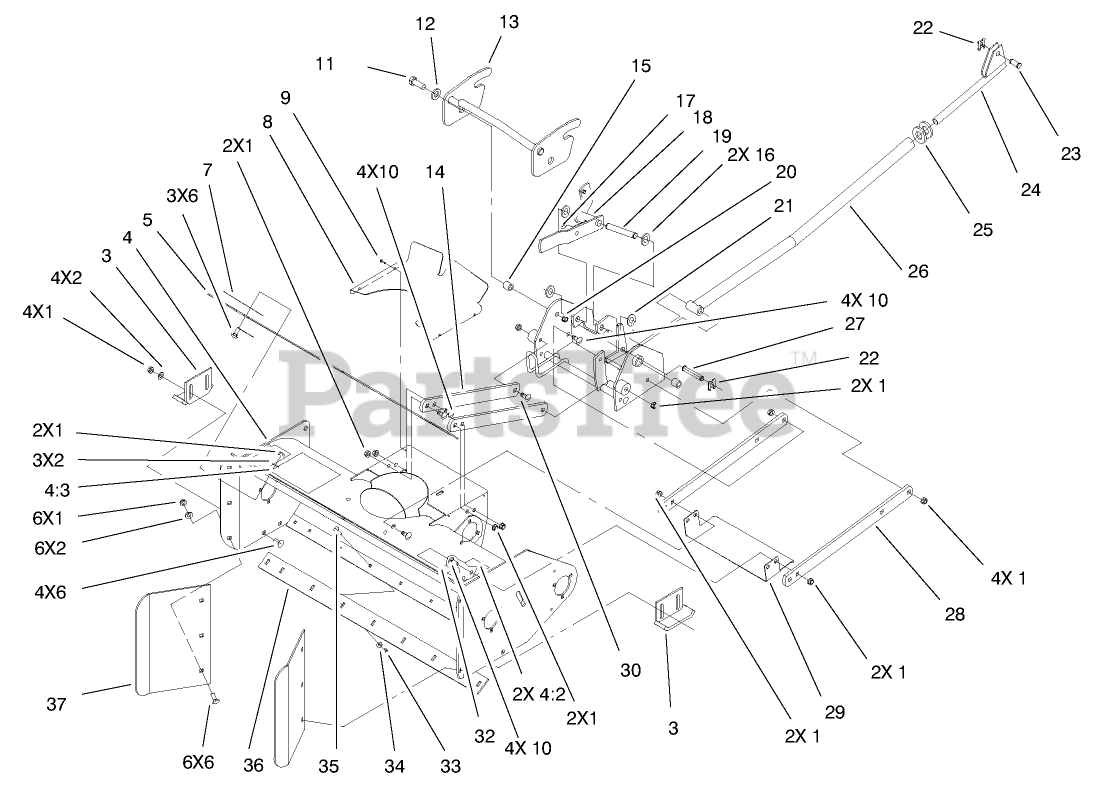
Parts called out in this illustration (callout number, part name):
1	NUT-LOCK, NI
2	WASHER-FLAT
4:2	DECAL-DANGER
4:3	DECAL-WARNING
5	PLATE-EXTENSION
6	BOLT-CARR
8	SHIELD-SNOW
9	SCREW-TAPTITE
10	Bolt
11	SCREW-HH
12	WASHER-FLAT
14	BAR-LIFT
15	BUSHING-PIVOT
16	WASHER-FLAT
17	FITTING-GREASE
18	PIVOT-IDLER
20	NUT-LOCK, NI
21	RING-RETAINING
22	CLIP-PIN
23	PIN-CLEVIS
25	WASHER-FLAT
27	PIN-CLEVIS
28	BAR-LIFT
29	SHIELD-LOWER
30	SCREW-CARR
32	Decal
33	NUT-LOCK, NI
34	WASHER-FLAT
37	PLATE-EXTENSION, RH
